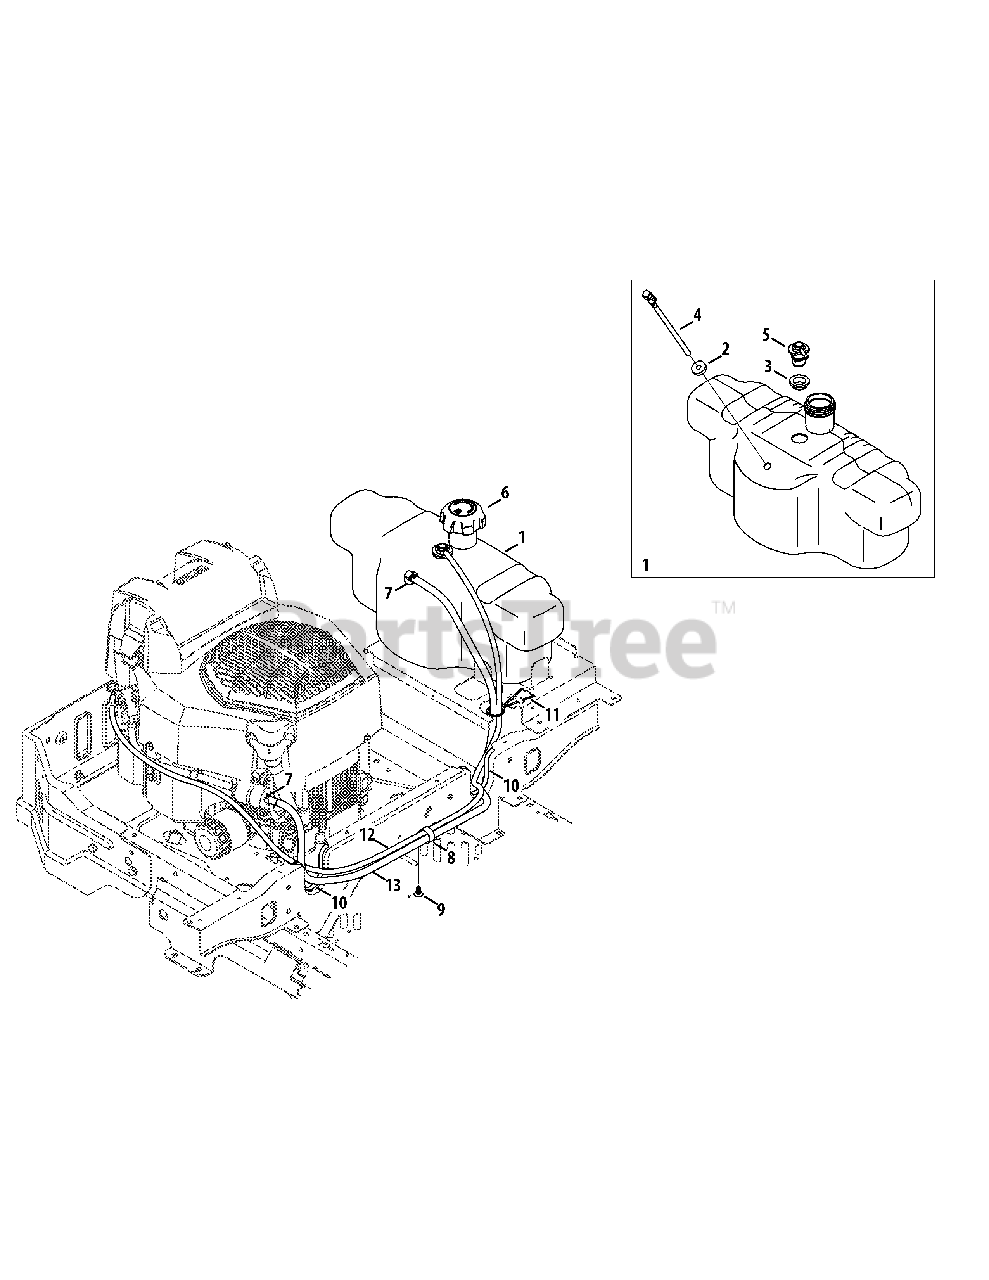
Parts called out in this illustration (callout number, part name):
1	Fuel Tank
2	Fuel Tank Bushing
3	Rubber Grommet
4	Fuel Pickup Fitting
5	Rollover Valve
6	Fuel Cap
7	Hose Clamp, .490 Dia.
8	Hose Clamp, 1.0
9	Ratchet Clip, .250
10	Trim Strip
11	Tank Support Rod
12	Fuel Hose, Low Permeation, 1/4
